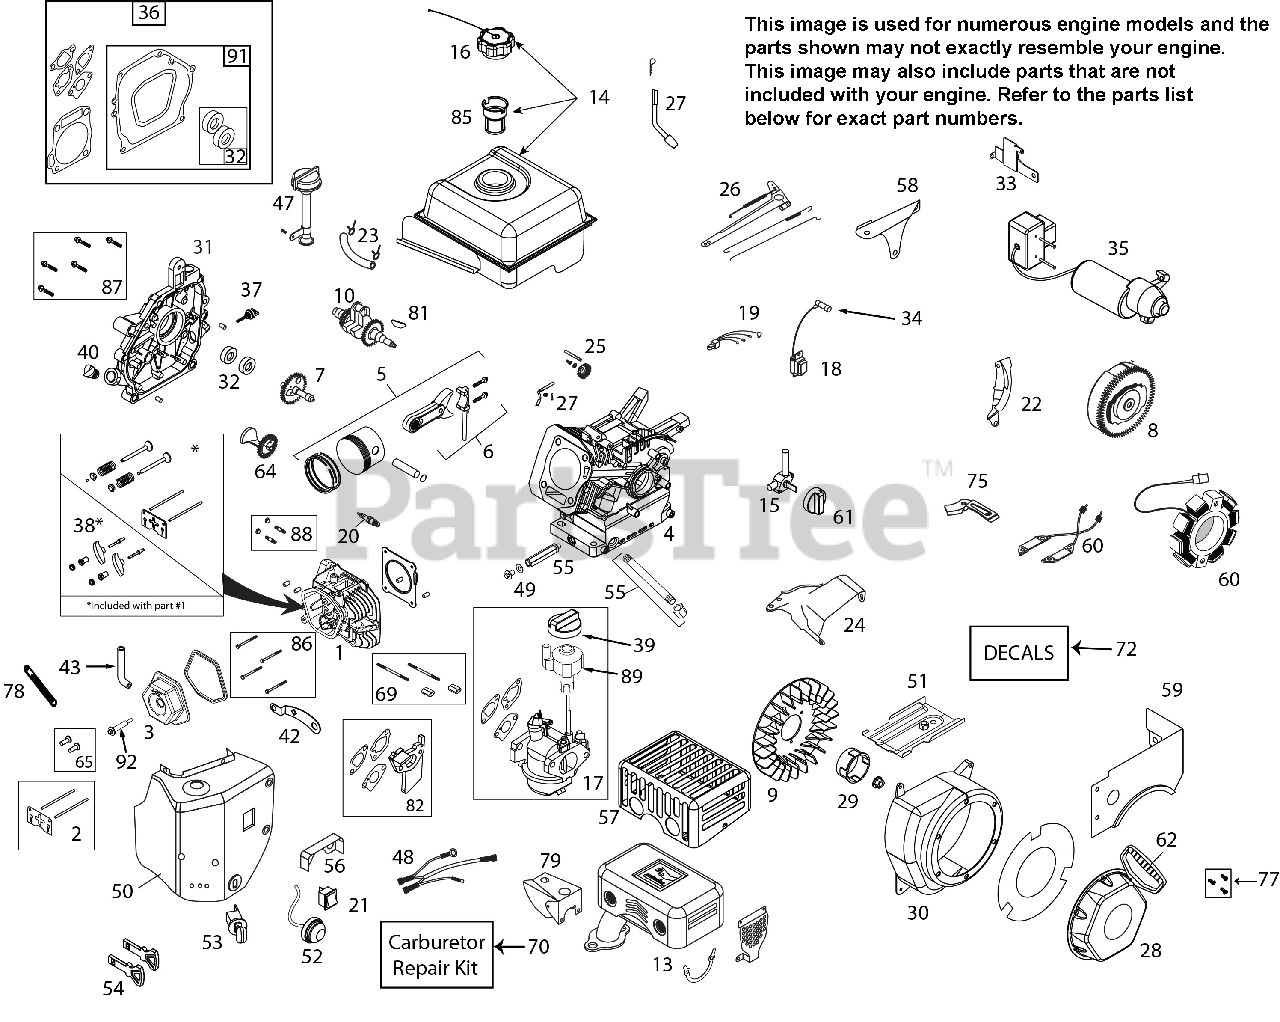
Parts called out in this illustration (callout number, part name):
1	CYLINDER HEAD ASSY (/GASKET)
2	PUSH ROD & PLATE KIT (W/GSKT)
3	VALVE COVER (W/GASKET)
4	CYLINDER - 414CC
5	PISTON & ROD ASSEMBLY
6	CONNECTING ROD ASSEMBLY
7	CAMSHAFT - MCR
8	FLYWHEEL - ELECTRIC START
9	COOLING FAN - FLYWHEEL
10	CRANKSHAFT (#17 KEYED)
13	MUFFLER ASSEMBLY - GEN III
14	FUEL TANK - LOW PROFILE
15	FUEL TANK ON/OFF VALVE
16	CAP, FUEL TANK RED
17	CARBURETOR (W/IDLE-DOWN)
18	IGNITION COIL (CDI) (STANDARD)
20	SPARK PLUG
23	FUEL HOSE KIT
24	SPEED CONTROL SHIELD (GEN III)
25	GOVERNOR GEAR ASSEMBLY
26	GOVERNOR ARM & LINK KIT
27	GOVERNOR ARM PADDLE
28	RECOIL STARTER, ROUND STYLE
29	STARTER CUP, ROUND STYLE
30	BLOWER HOUSING - MATTE BLACK
31	CRANKCASE COVER
32	OIL SEAL KIT
33	ELECT START SWITCHBOX BRACKET
34	SPARK PLUG BOOT (W/MTL SHIELD)
35	120V ELECTRIC STARTER
36	ENGINE GASKET KIT
37	SMALL BLACK OIL DIPSTICK
38	ROCKER ARM KIT (W/GASKET)
39	CHOKE CONTROL KNOB (RED)
40	NON-REMOVABLE PLASTIC PLUG
43	BREATHER TUBE
47	HIGH OIL-FILL TUBE & CAP
48	WIRE HARNESS
49	OIL DRAIN PLUG (W/WASHER)
50	HEATER BOX KIT (369/414CC)
51	SHIELD - CYLINDER
52	PRIMER BULB WITH HOSE
53	KEY SWITCH, STOP-RUN (W/KEYS)
54	KEY SET (2) (RED)
55	FRONT OIL DRN PIPE & NUT ASSY
56	CARBURETOR VAPOR SHIELD
57	MUFFLER HEAT SHIELD - GEN III
58	SHIELD - GOVERNOR LINKAGE
59	FUEL TANK SKIRT (369/414CC)
60	CHARGING COIL (60-WATT AC)
61	FUEL CONTROL KNOB (RED)
62	STARTER GRIP-SNOW (DELUXE)
64	COUNTER WEIGHT KIT
65	TAPPET KIT (SET OF 2)
69	CARB MTG STUD KIT 414CC
70	CARBURETOR REPAIR KIT
72	LABEL KIT-SNOW (2016)
75	SHIELD - FLYWHEEL
77	RECOIL BOLT KIT
78	BREATHER TUBE RETAINING STRAP
79	SHIELD - CARBURETOR COVER
81	WOODRUFF FLYWHEEL KEY 5-PACK
82	CARBURETOR SPACER
86	HEAD BOLT KIT 291-414CC
87	CRANKCASE COVER BOLT KIT 414CC
88	MUFFLER SHOULDER BOLT
89	SPEED CONTROL KNOB
91	CRANKCASE GASKET KIT(369-414)
92	VALVE COVER BOLT (SINGLE BOLT)
9999	HIGH ALT JET - 414CC L12 CARB
9999	HARDWARE KIT (4 M6X10 FLG BLT)
